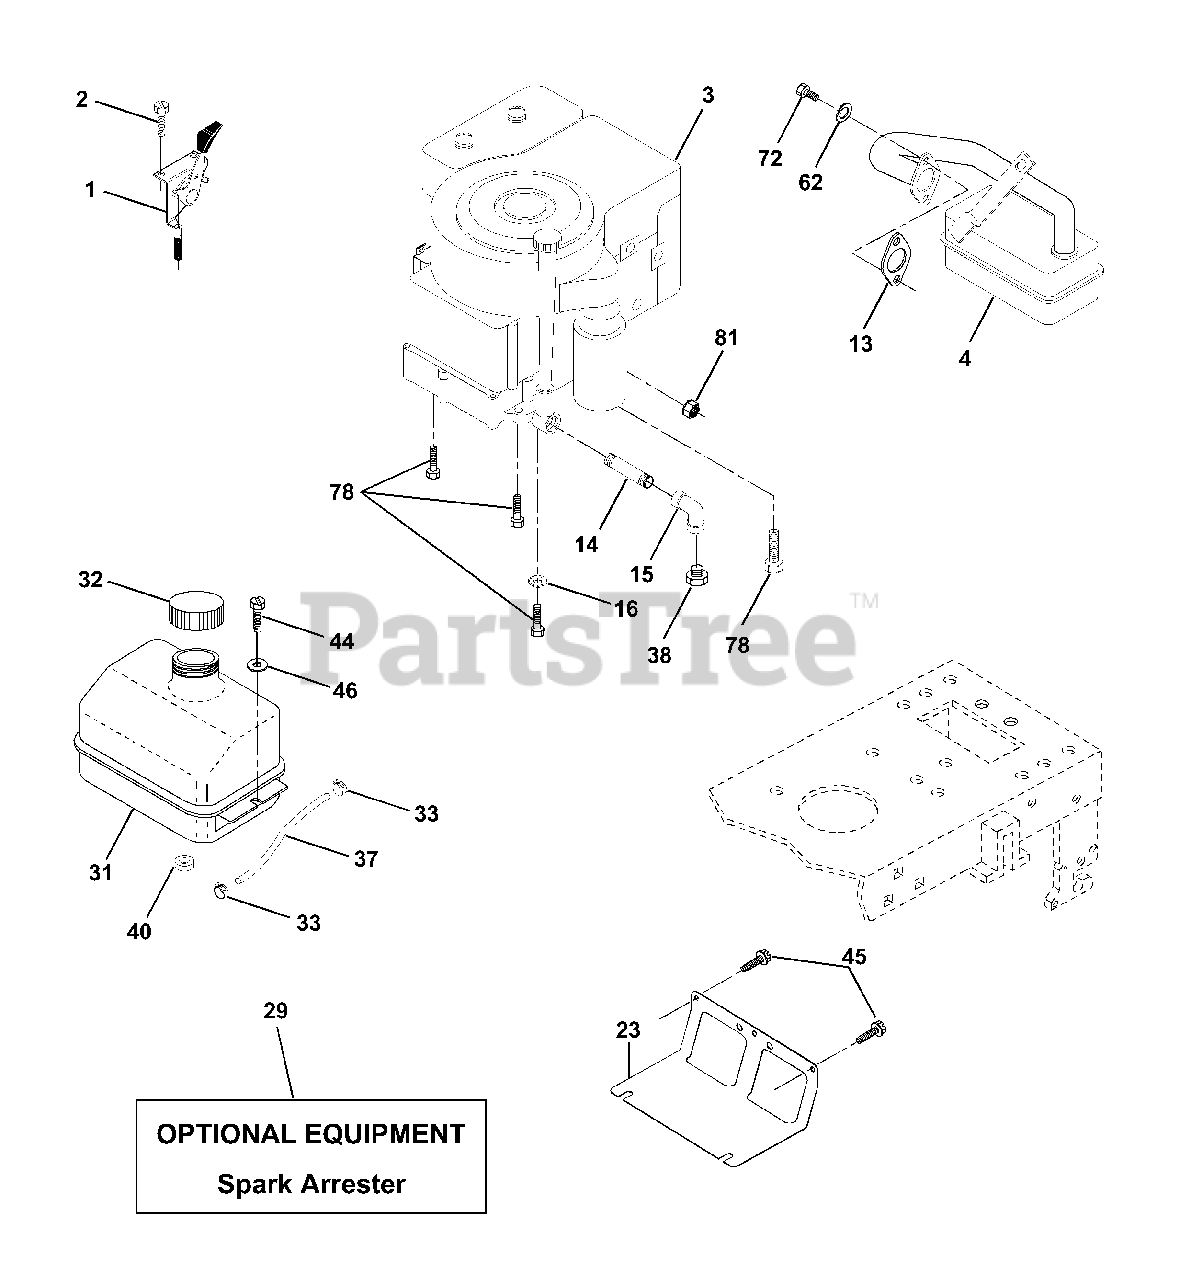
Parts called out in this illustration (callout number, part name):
1	Control Throt /Ch 23.5 Lh Flag
2	Screw Hex Thd Cut 1/4-20x5/8 T
4	Muffler Exhaust B&S Lt
13	Gasket 1 313 Id Tin Plated
14	Nipple Pipe 3/8 Npt X 3"
15	Elbow Std 90 Degree 3/8-18 Npt
16	Washer Lock Ext Tooth 3/8
23	Shield Browning/Debris Guard
29	Arrestor Spark
31	Tank Fuel 1 25 Fr
32	Cap Asm Fuel W/sym Vented
33	Clamp Hose Blk
37	Line Fuel 20"
38	Plug Oil Drain
40	Bushing Snap Nyl Blk Fuel Line
44	Screw Hexwsh Thdrol 1/4-20x3/4
45	Screw Hex Wsh Thdrol 3/8-16
46	Washer 9/32 X 7/8 X 16ga
62	Washer Lock Hvy Hlcl Spr 5/16
72	Screw Hexhd Cap 5/16-18x3/4
78	Screw Thdrol 3/8-16x1-1/4 Tytt
81	Nut Keps Hex 1/4-20 Unc
